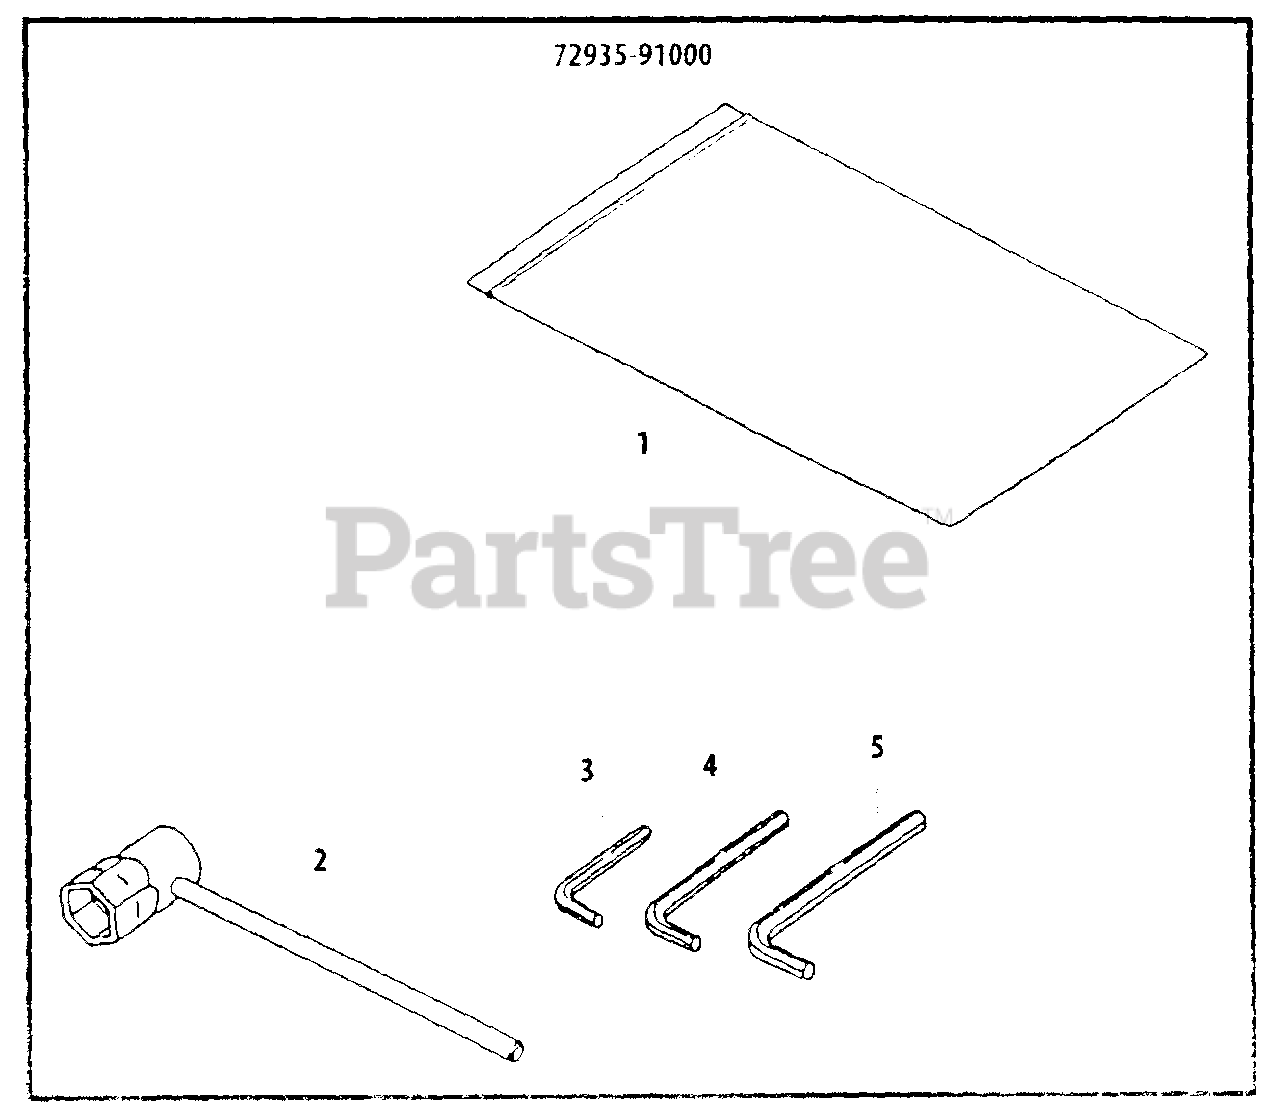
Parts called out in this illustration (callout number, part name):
1	BAG, TOOL
2	T-WRENCH 19 MM
3	WRENCH, ALLEN 3 MM
4	WRENCH, ALLEN 4 MM
5	WRENCH, ALLEN 5 MM
72935-91000	TOOL KIT, SERVICE
